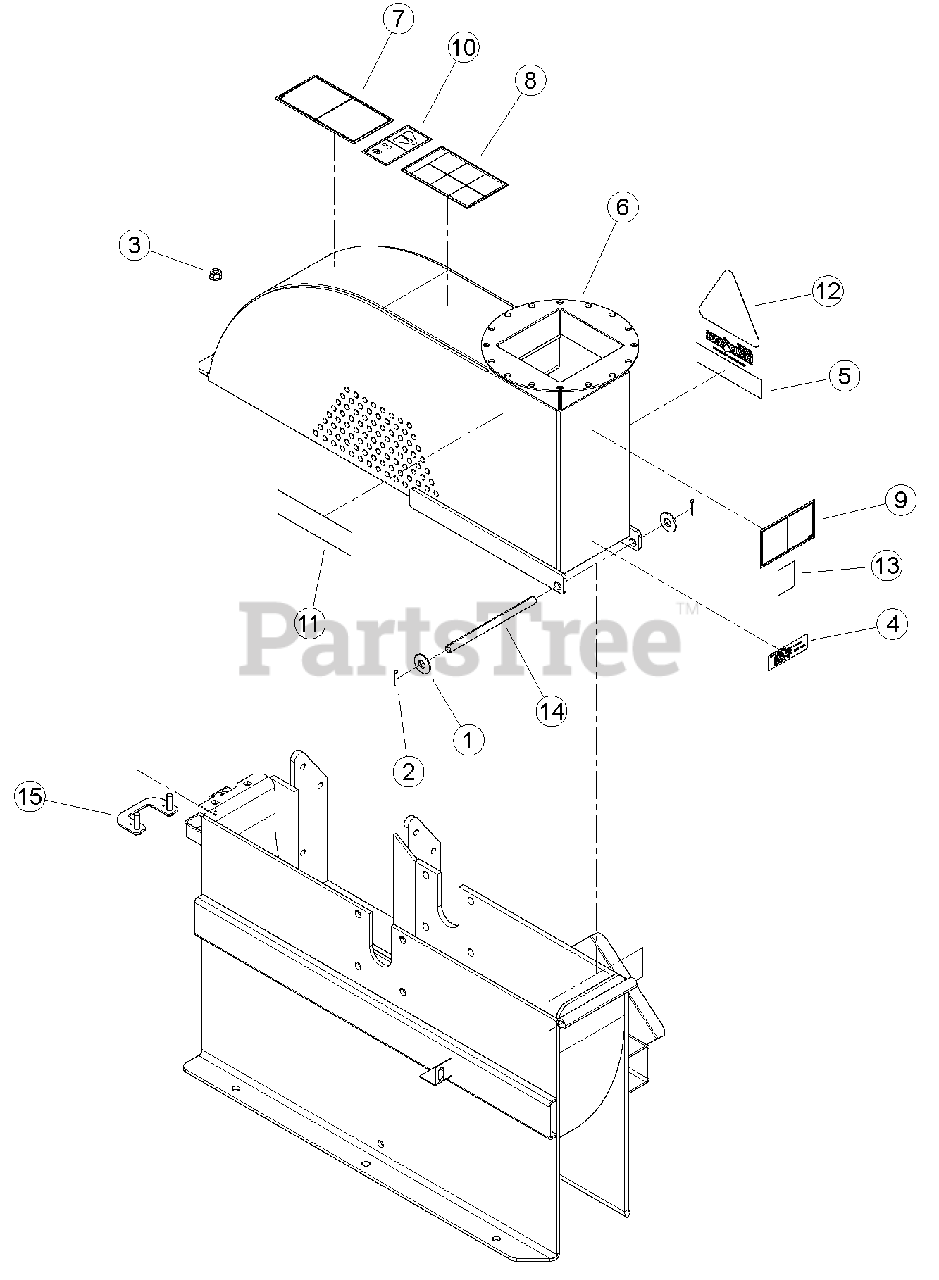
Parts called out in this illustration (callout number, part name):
1	WASHER, 1/2" FLAT ZP
2	PIN, 1/8 X 1.00 ZP COTTER
3	NUT, 3/8-16 NYLOCK FLANGE
4	DECAL, ATLANTIC BRIDGE LTD INFO (CE COMPLIANT ONLY)
5	DECAL, MODEL CH911DH
6	ASSEMBLY, CHIPPER COVER W/ DECALS
7	DECAL, KNIFE ACCESS ISO
8	DECAL, OPERATING INSTRUCTIONS ISO
9	DECAL, DISCHARGE ISO
10	DECAL, MAINTENANCE ISO
11	DECAL, ECHO BEARCAT 6.82 X 1.90
12	DECAL, CHIP IT
13	DECAL, ECHO BEARCAT QR CODE
14	SHAFT CHIPPER TOP PIVOT
15	WELDMENT, CHIPPER HOUSING ACCESS
